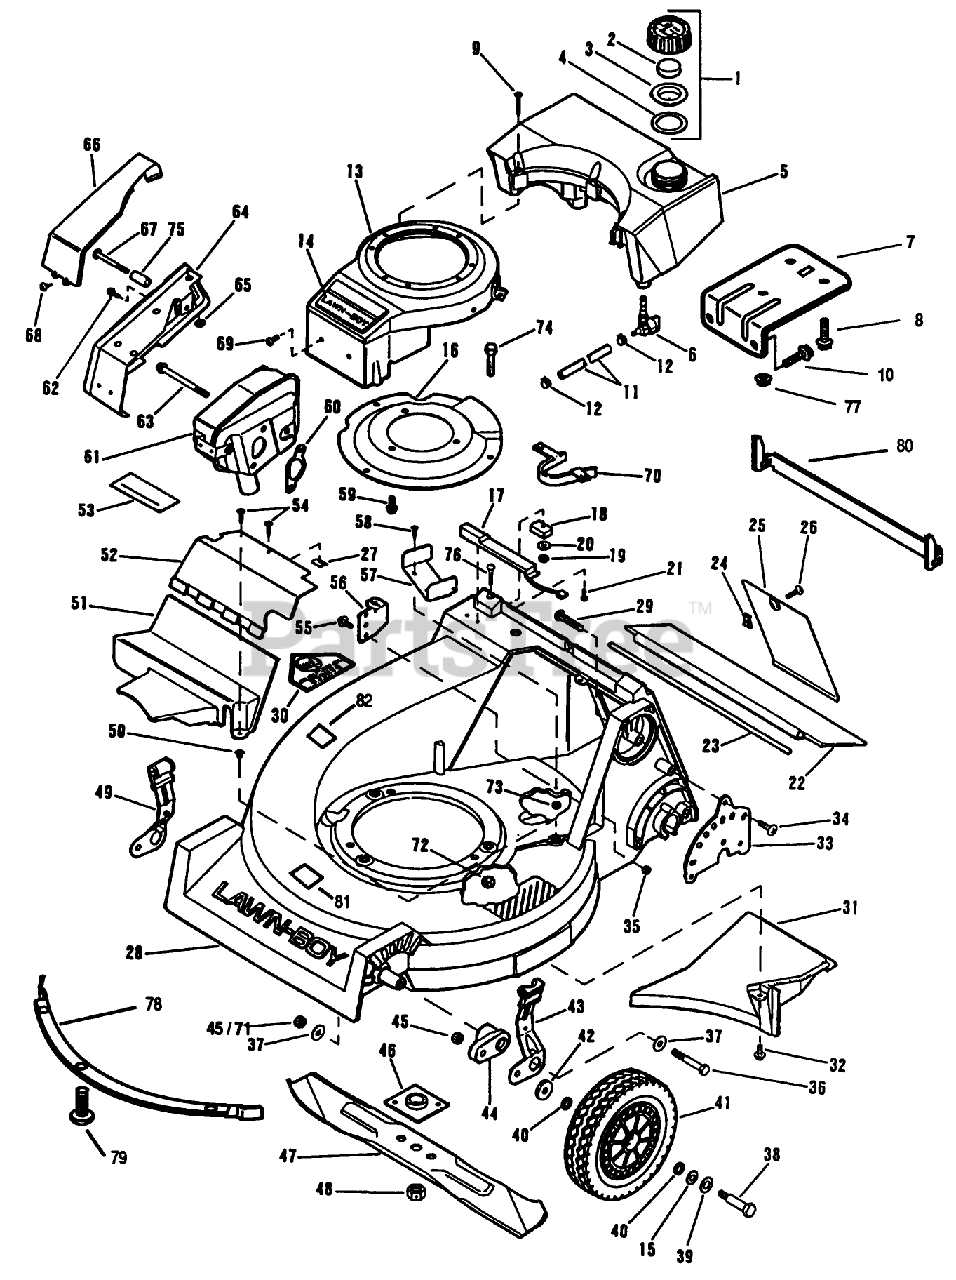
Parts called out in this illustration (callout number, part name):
1	CAP AY - F/OIL SM
2	BAFFLE - FOAM SM
4	GASKET-FUELCAP SM
6	DISC/LB SER.BUL.#6
7	DISC. LB SER.BUL.#6
8	DISC/LB SER.BUL.#6
9	DISC.LB SER.BUL.#6
11	GAS LINE SM
12	HOSE CLAMP SM
14	APPLIQUE SM
15	WASHER
16	PLATE SM
24	SPEED NUT LARSON
25	DOOR-ACCESS ELECT.
26	SCREW-CROSS RECESS
27	NUT-SPEED
31	CHUTE BAFFLE NYL
33	PLATE HGT CMS
34	SCREW-BHTF
35	LOCKNUT E
37	WASHER-PLAIN
38	BOLT WHEEL QUAL
39	SPACER
40	WASHER
41	WHEEL&TIRE 8" TRI
42	WASHER
43	KNOB & SPRING CMS
44	ARM HGT ADJ *BLACK
45	NUT-JAM, LOCKING
46	PLATE AND COLLAR ASM
48	NUT-BLADE
49	KNOB & SPRING CMS
50	NUT-CLIP
57	BELT GUIDELB
60	GASKET - EXH SM
62	SCREW S
63	SCREW-SEMS
64	MUFFLER GUARD&COVR
65	NUT-PUSH
66	COVER MUFFLER CP
67	SCREW SM
68	SCREW SM
71	LOCKNUT
72	NUT-LOCK F
73	NUT C/LOCK E
74	SCREW-HH
75	SPACER S
